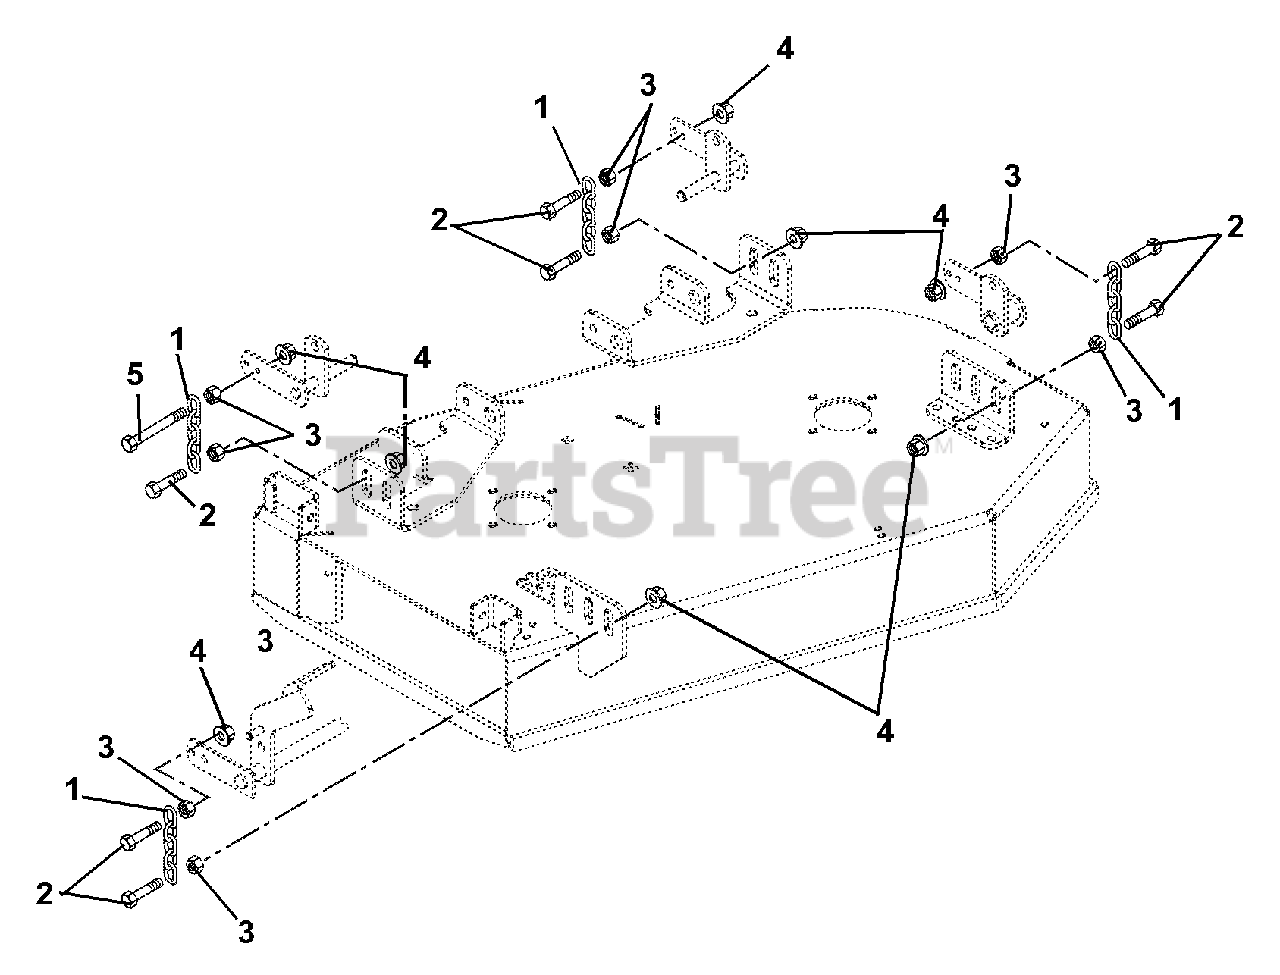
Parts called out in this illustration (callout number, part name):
1	CHAIN, LINK
2	BLT-HEX M12X1.75X55 GR5 YZ
3	NUT-SPNLK-FLG M12-1.75 YZ
4	NUT-LK-TOP-FLG M12-1.75 YZ
5	@BLT-HEX .50-13X3.00 GR5 YWZC
